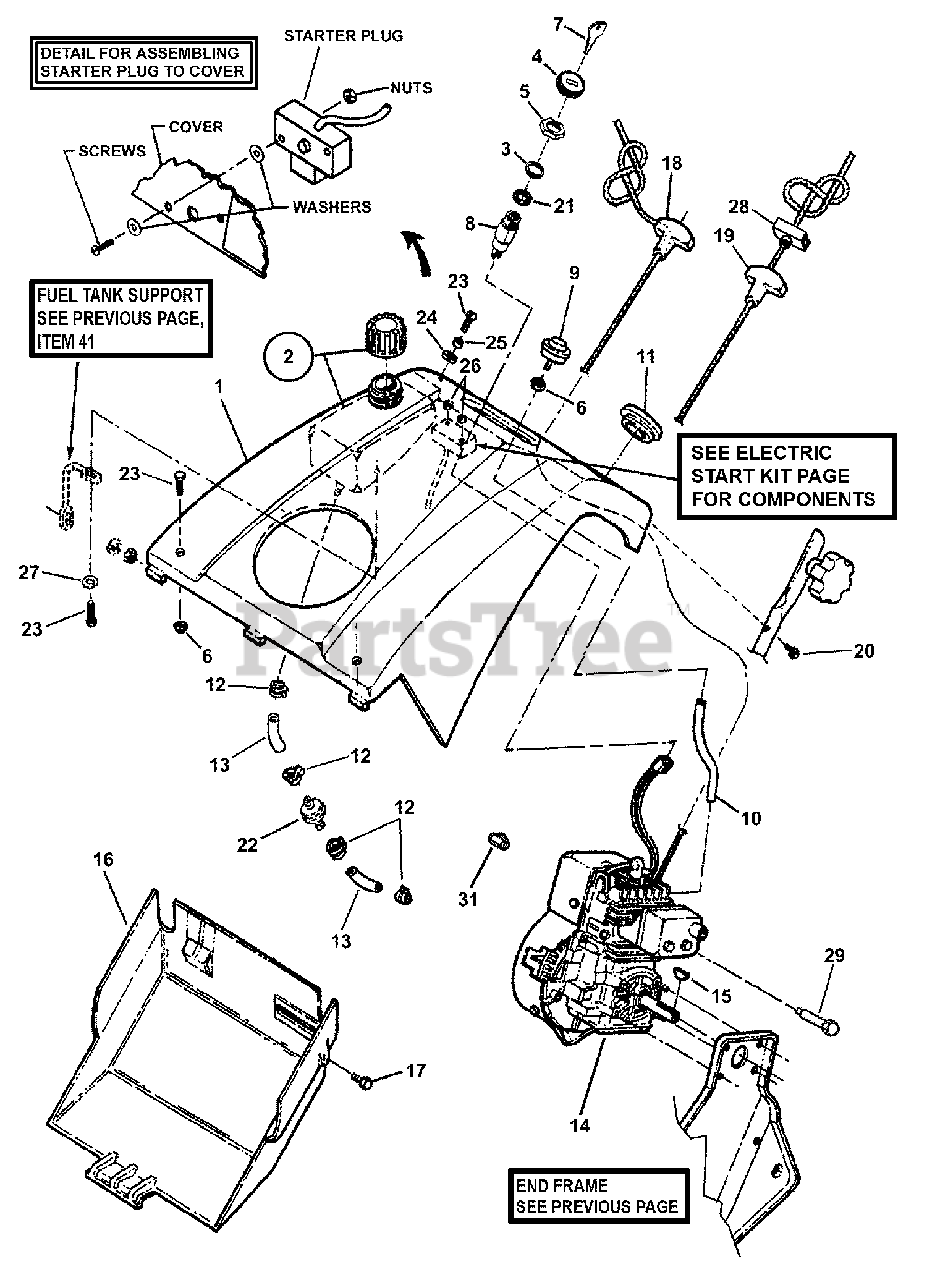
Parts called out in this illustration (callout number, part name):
1	COVER, Top (includes Eyelet # 24636)
2	ASSEMBLY, Fuel Tank (includes Cap # 24495)
3	SPACER
4	BEZEL
5	NUT, 5/8-32 Hex
6	NUT, 1/4-20 Hex Flange lock
7	KEY (Pair)
8	SWITCH, Ignition
9	PRIMER
10	HOSE, Primer
11	PLUG, Hole
12	CLAMP, Fuel Hose
13	HOSE, Fuel
14	* ENGINE, 3 HP Tecumseh (HSK 600-1683T)
14	* ENGINE, 3 HP Tecumseh (HSK 600-1691T)
14	* ENGINE, 3 HP Tecumseh (HSK 600-1702T)
14	* ENGINE, 3 HP Tecumseh (TH098SA-1732E)
14	* ENGINE, 3 HP Tecumseh (TH098SA-1733E)
14	* ENGINE, 3 HP Tecumseh (TH098SA-1734E)
15	KEY, 5/32 x 5/8" Woodruff
16	COVER, Bottom
17	SCREW, #10-24 x 1/2" Hex Washer Self-Tap (Torx)
18	HANDLE, Pull Rope
19	HANDLE, Pull Rope
20	SCREW, #8 x 1-1/4" Hi-Lo Self-Tap
21	WASHER, 5/8" Internal Tooth Lock
22	FILTER, In-Line
23	SCREW, 1/4-20 x 3/4" Hex Head Cap, GR 5
24	ISOLATOR, Fuel Tank/Cover
25	SPACER
26	WASHER, #10 Flat
27	WASHER, 1/4" Split Lock
28	INSERT, Starter Handle
29	MUFFLER STUD
31	KNOB, Red
